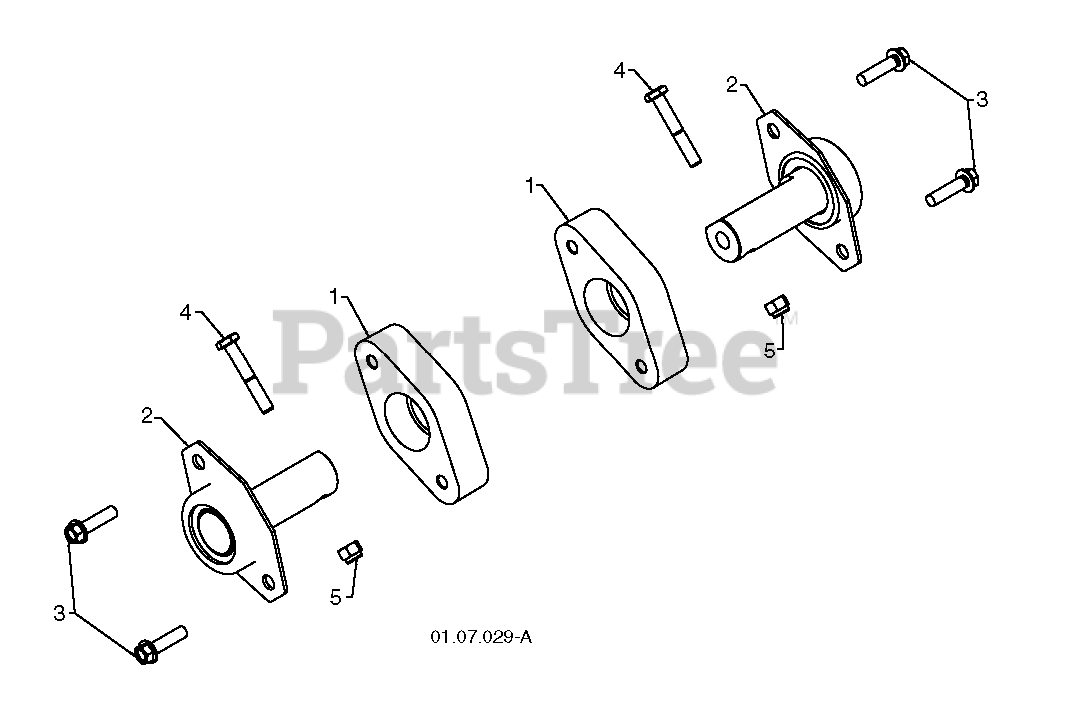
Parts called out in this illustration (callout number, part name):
1	RETAINER.PLASTIC
2	BEARING.BALL.AUGER.FLAT.
3	SCREW, HEX HD 5/16X1
4	SCREW.HEX.HD1/4-20X
5	LOCKNUT.NYLOC.1/4-20
